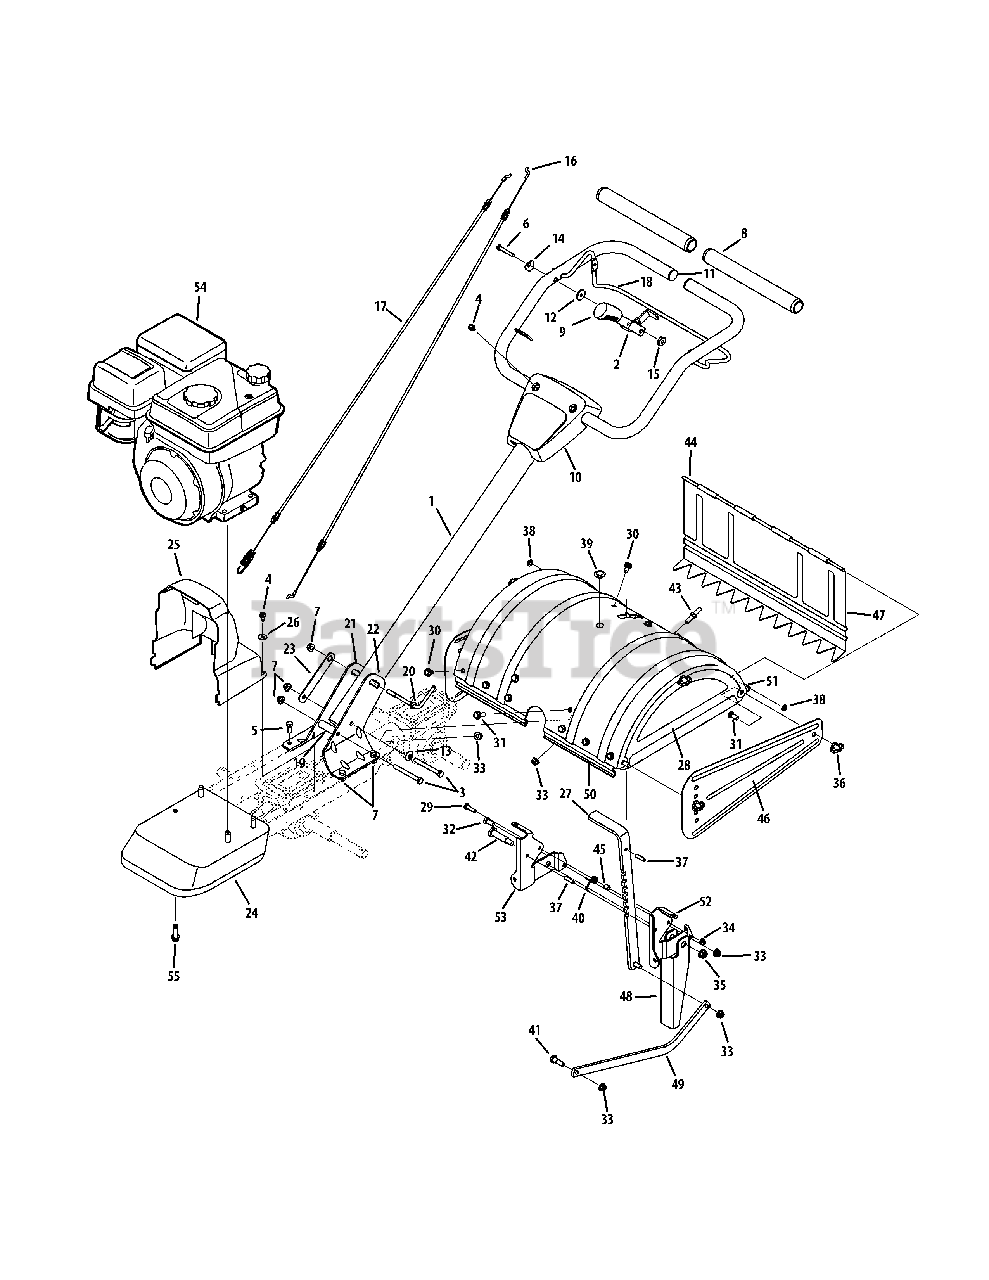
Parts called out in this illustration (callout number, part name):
3	Hex Screw, 5/16-18 x 3.00
4	Hex Washer Screw, 1/4-20 x 0.500
5	Hex Washer Screw, 5/16-18 x .875
6	Hex Lock Screw, 1/4-20 x 1.62
7	Flange Lock Nut, 5/16-18
8	Foam Grip, .970 x 11.0
9	Selector Handle
10	Handle Cover, 400
11	End Plug
12	Flat Washer, .265 x .938 x .120
13	Bell Washer, .340 x .872 x .060
14	Saddle Washer, .320 x .93 x .060
15	Shoulder Spacer, .375 x .165
16	Reverse Cable
17	Forward Cable
18	Bail, Clutch
19	Spacer, .322 x .625 x 2.00
20	Handle Adjustment Crank
23	400 Nut Retainer Bracket
25	Belt Cover
26	Flat Washer, .28 x .74 x .063
29	Hex Screw, 1/4-20 x 1.00
30	Hex Washer Screw, 5/16-18 x 0.625
31	Hex Washer Screw, 5/16-18 x .875
32	Hex Screw, 5/16-18 x .75
33	Flange Lock Nut, 5/16-18
34	Flange Lock Nut, 1/4-20
35	Flange Lock Nut, 3/8-16
36	Wing Nut w/ Bell Washer, 5/16-18
37	Spring Pin, 1/4 x 1.00
38	Cap Speed Nut, 1/4
39	Deck Hole Plug
40	Torsion Spring
41	Shoulder Screw, 5/16-18 x .405 x .345
42	Shoulder Screw, .498 x 1.635
43	Hex Screw, 5/16-18 x .75
44	Tiller Flap Rod
45	Round Spacer, .370 x .260 x .410
54	Replacement Engine
